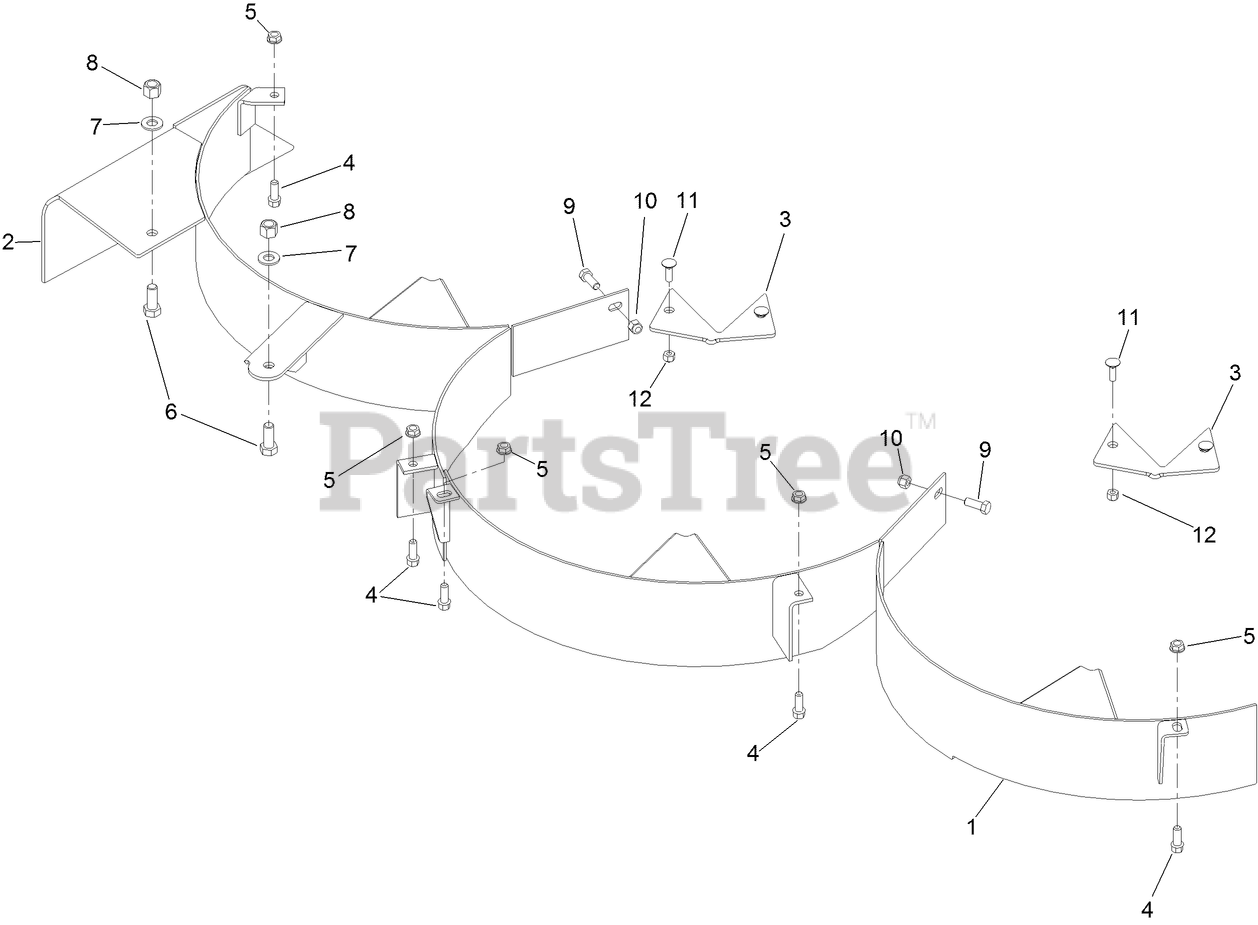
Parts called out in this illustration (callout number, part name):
1	BAFFLE ASM LH
2	BAFFLE ASM RH
5	NUT-HHF, WHIZ
6	SCREW-HH
7	WASHER-FLAT
8	NUT-LOCK, NI
9	SCREW-HH
10	NUT-LOCK, NI
11	BOLT-CARR
12	NUT-LOCK, NI
